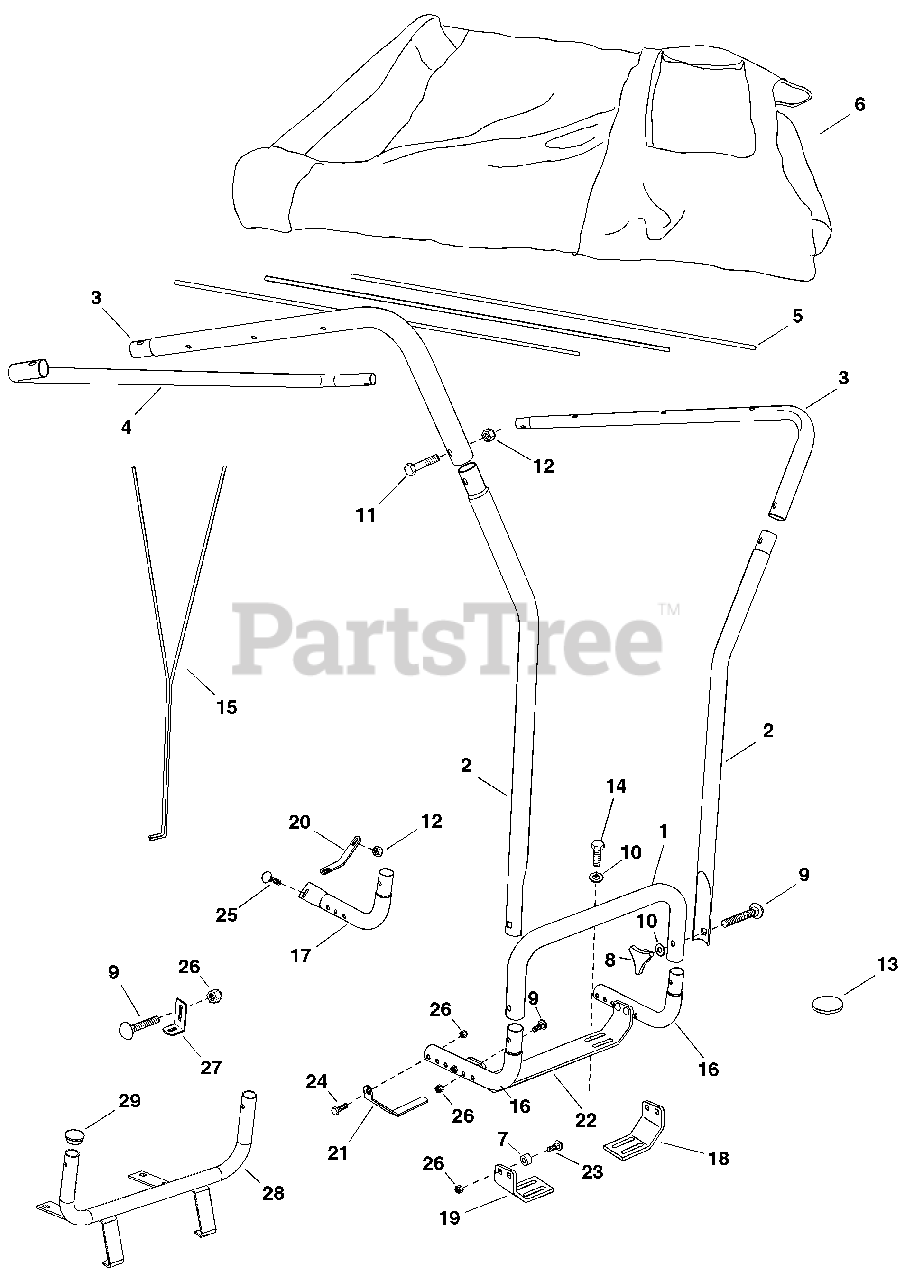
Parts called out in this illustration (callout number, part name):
1	Upper Base Tube
2	Upright Tube
3	Top Tube
5	Support Rod
6	Vinyl Canopy
8	Plastic Knob
9	Carriage Bolt, 5/16-18 x 2"
10	Flat Washer, 5/16"
11	Hex Bolt, 1/4-20 x 1-1/2"
12	Nylock Nut, 1/4-20
13	Adhesive Pad
14	Hex Bolt, 5/16-18 x 1"
15	Front Brace Rod
16	Base Leg Tube
17	Base Leg Tube, Flattened
18	Right Base Bracket
19	Left Base Bracket
20	Right Support Bracket
21	Left Support Bracket
22	Base Bracket
23	Carriage Bolt, 5/16-18 x 2-3/4"
24	Hex Bolt, 5/16-18 x 2"
25	Carriage Bolt, 1/4-20 x 1"
26	Nylock Nut, 5/16-18
27	Rear Support Bracket
28	Base Bracket Assembly
29	Plastic Cap
